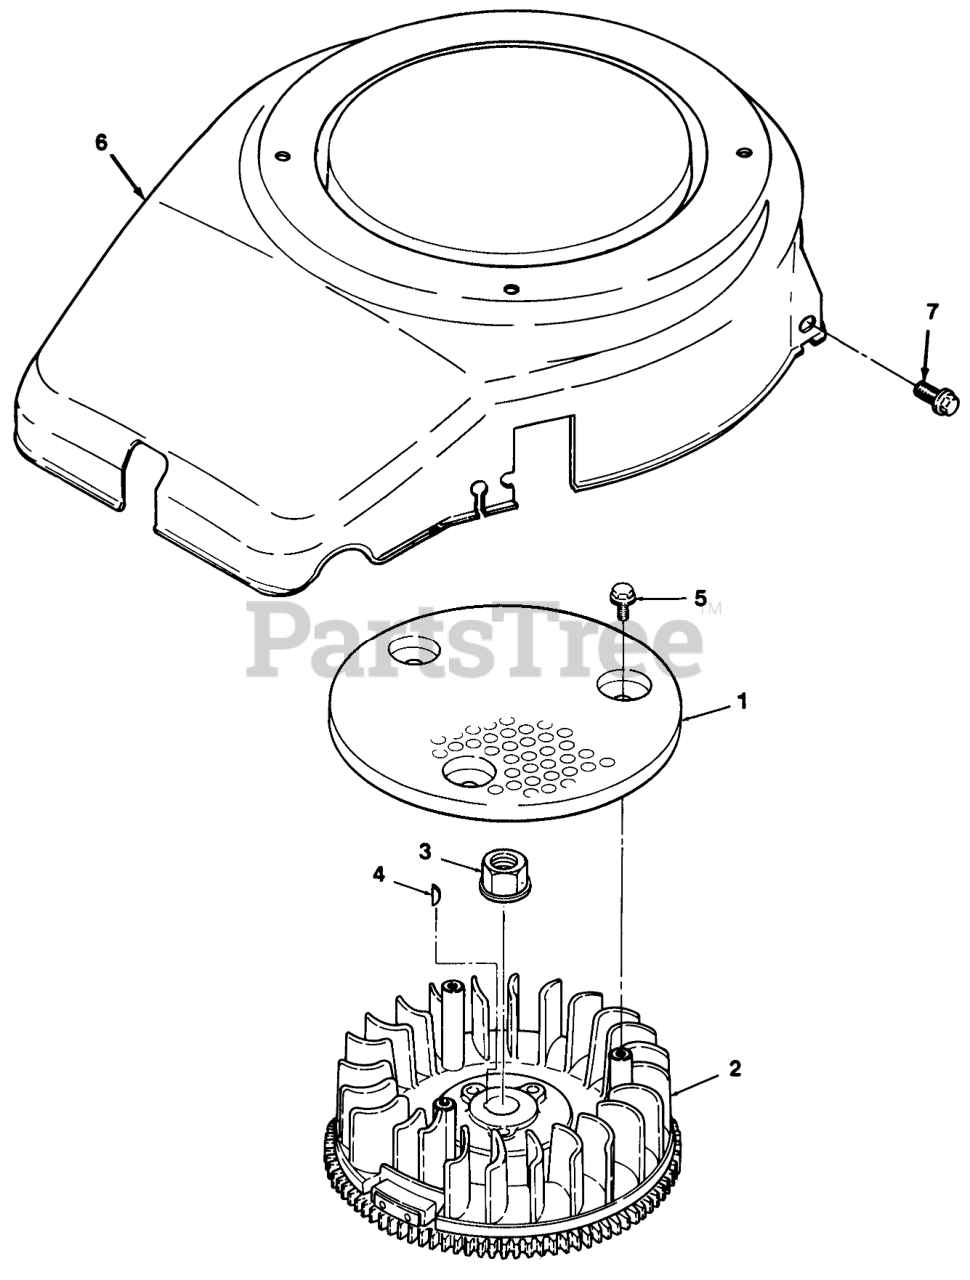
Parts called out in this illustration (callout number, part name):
1	Screen
1	STARTER
2	WHL-ASS'Y BLOWER
2	Screw
4	Screw-Hex Hd.
5	NUT-FLANGE M18
6	Blower Housing
7	BOLT-HHF M6 X 12MM
